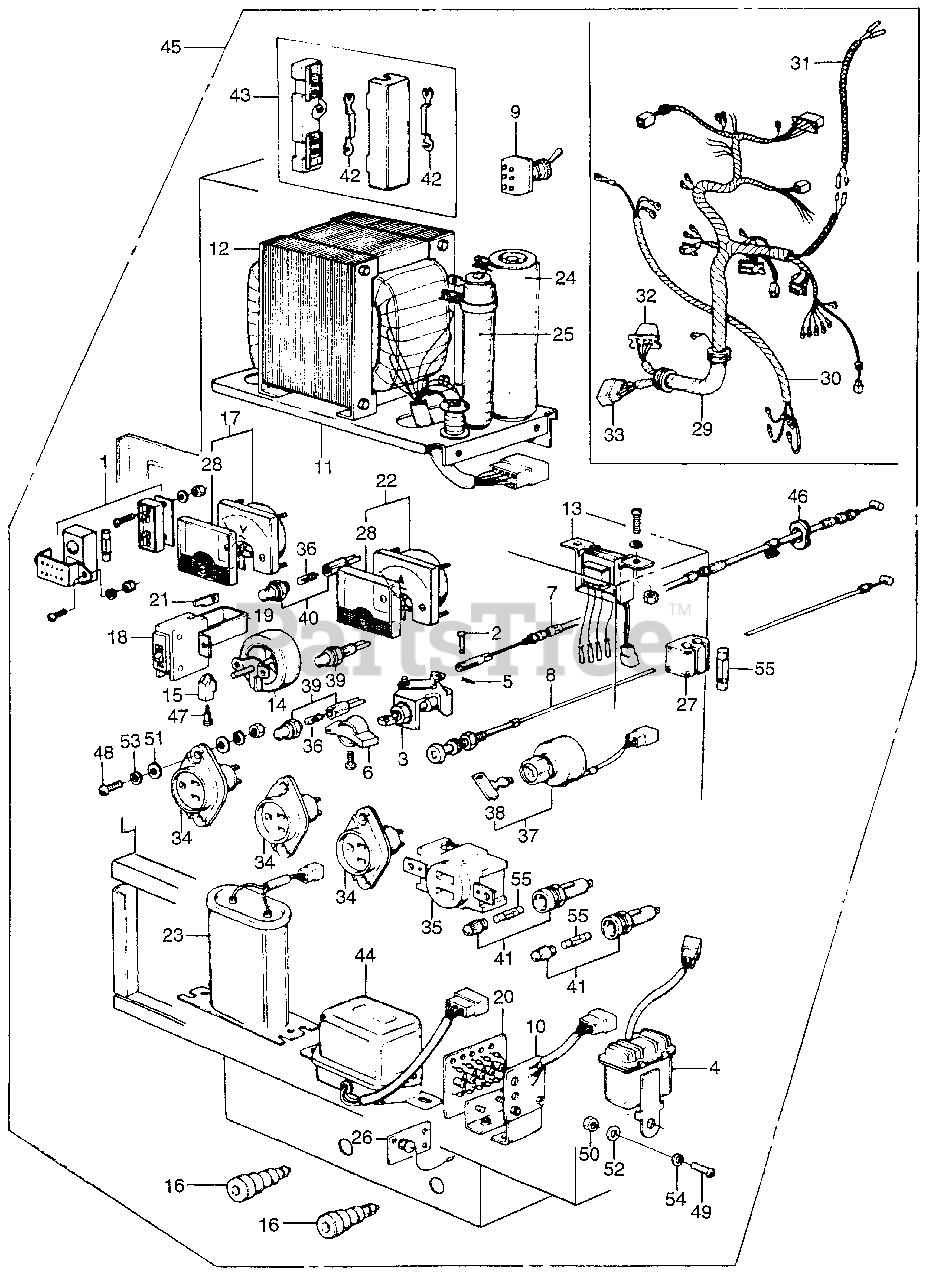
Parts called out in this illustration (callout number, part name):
1	BELT KIT (NOT AVAILABLE)
2	PIN, DECOMPRESSION LEVER
3	CONTROL ASSY., ENGINE
4	RELAY ASSY., FUEL CUT (NOT AVAILABLE)
5	PIN, SNAP (3MM)
6	KNOB, ENGINE CONTROL (NOT AVAILABLE)
7	CABLE, THROTTLE (NOT AVAILABLE)
8	CABLE, CHOKE (NOT AVAILABLE)
9	SWITCH ASSY. (NOT AVAILABLE)
10	DIODE STACK
11	HOLDER, CURRENT TRANSFORMER
12	TRANSFORMER, CURRENT
13	TRANSFORMER, OVERRUN
14	RESISTOR, VARIABLE (NOT AVAILABLE)
15	KNOB, ADJUSTING
16	TERMINAL, A.C.
17	VOLTMETER (150V, 300V SCALE) (NOT AVAILABLE)
17	VOLTMETER (150V, 300V SCALE)
18	BREAKER, CIRCUIT (43A) (NOT AVAILABLE)
19	HOLDER, BREAKER (NOT AVAILABLE)
20	DIODE STACK ASSY.
21	TERMINAL, BREAKER
22	METER, AMPERE (6A SCALE) (NOT AVAILABLE)
23	CONDENSER ASSY.
24	RESISTOR SET (NOT AVAILABLE)
25	RESISTOR, ADJUSTABLE
26	DIODE ASSY., D.C. CHARGING
28	LENS, METER (NOT AVAILABLE)
29	WIRE HARNESS, D.C. ALTERNATOR
30	WIRE HARNESS, ALTERNATOR
31	WIRE HARNESS A
32	CONNECTOR, POLE MALE (6)
33	CONNECTOR, POLE MALE (8) (NOT AVAILABLE)
34	RECEPTACLE (10A 250V)
35	RECEPTACLE (30A)
36	BULB (12V2W)
37	SWITCH ASSY., COMBINATION (NOT AVAILABLE)
39	SOCKET ASSY., PILOT LAMP (NOT AVAILABLE)
40	SOCKET ASSY., PILOT LAMP (NOT AVAILABLE)
41	HOLDER ASSY., FUSE
42	FUSE (20A) (NOT AVAILABLE)
43	BOX ASSY., MAIN FUSE (NOT AVAILABLE)
44	RELAY ASSY., OVERRUN
45	BOX ASSY., CONTROL *NH83L* (OFF BLACK)
46	GROMMET, AIR CLEANER HOUSING
47	BOLT, KNOB (NOT AVAILABLE)
48	SCREW, PAN (4X12)
49	SCREW, PAN (6X12)
50	NUT, HEX. (6MM)
51	WASHER, PLAIN (4MM)
52	WASHER, PLAIN (6MM)
53	WASHER, SPRING (4MM)
54	WASHER, SPRING (6MM)
55	FUSE B (15A)
